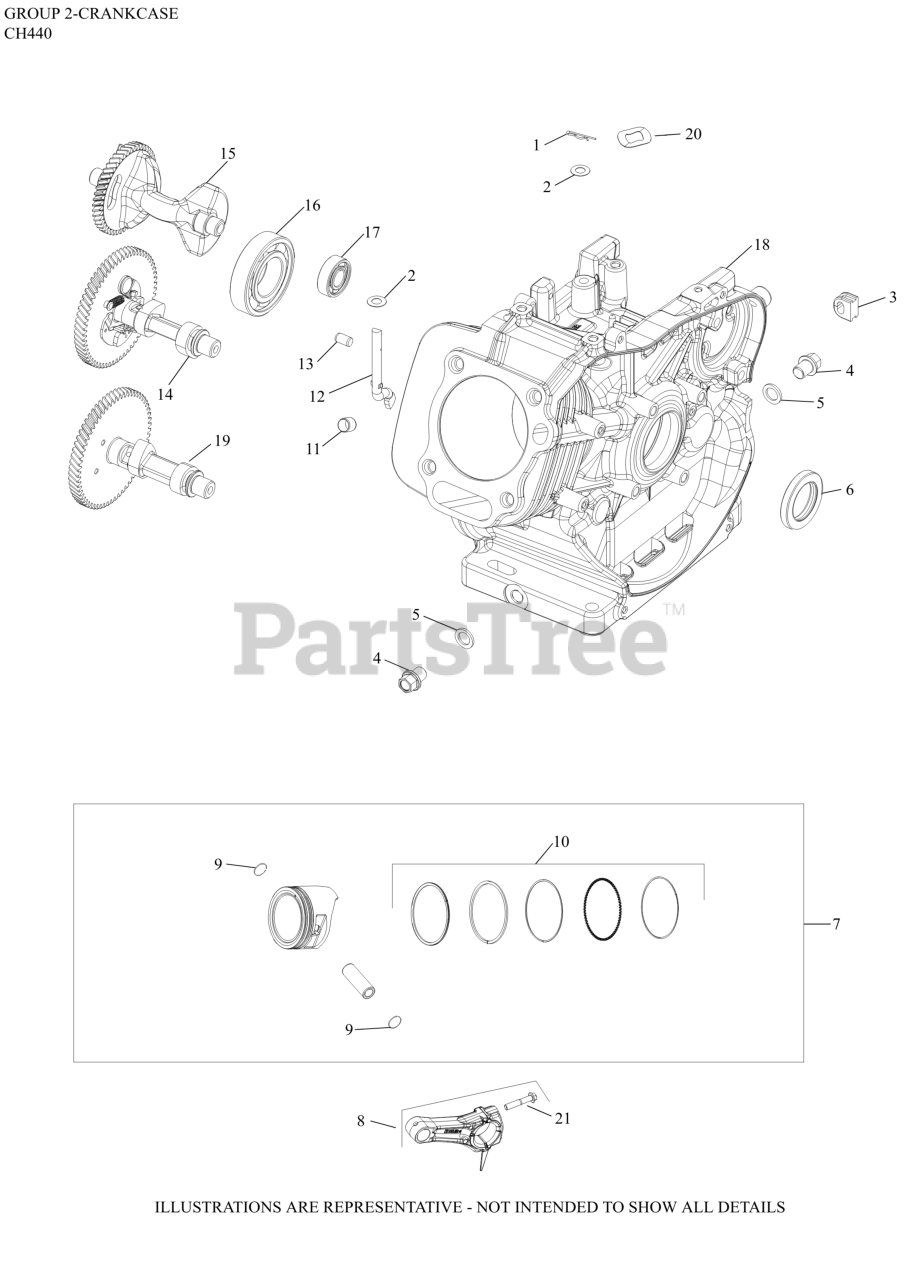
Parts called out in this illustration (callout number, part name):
1	CLIP, GOVERNOR SHAFT
2	WASHER, FLAT
3	GROMMET, CRANKCASE
4	KIT, DRAIN PLUG
5	WASHER, DRAIN PLUG
6	SEAL, CRANKSHAFT
7	KIT, PISTON W/RING SET (STD)
7	KIT, PISTON (0.25 O.S.)
8	ROD, CONNECTING ASSEMBLY-(#1706714S)
9	RETAINER, PISTON
11	PIN, DOWEL CYLINDER HEAD
12	SHAFT, GOVERNOR CROSS
13	PIN, DOWEL
14	CAMSHAFT ASSEMBLY
15	SHAFT, BALANCE
18	CRANKCASE
19	CAMSHAFT, NO ACR
